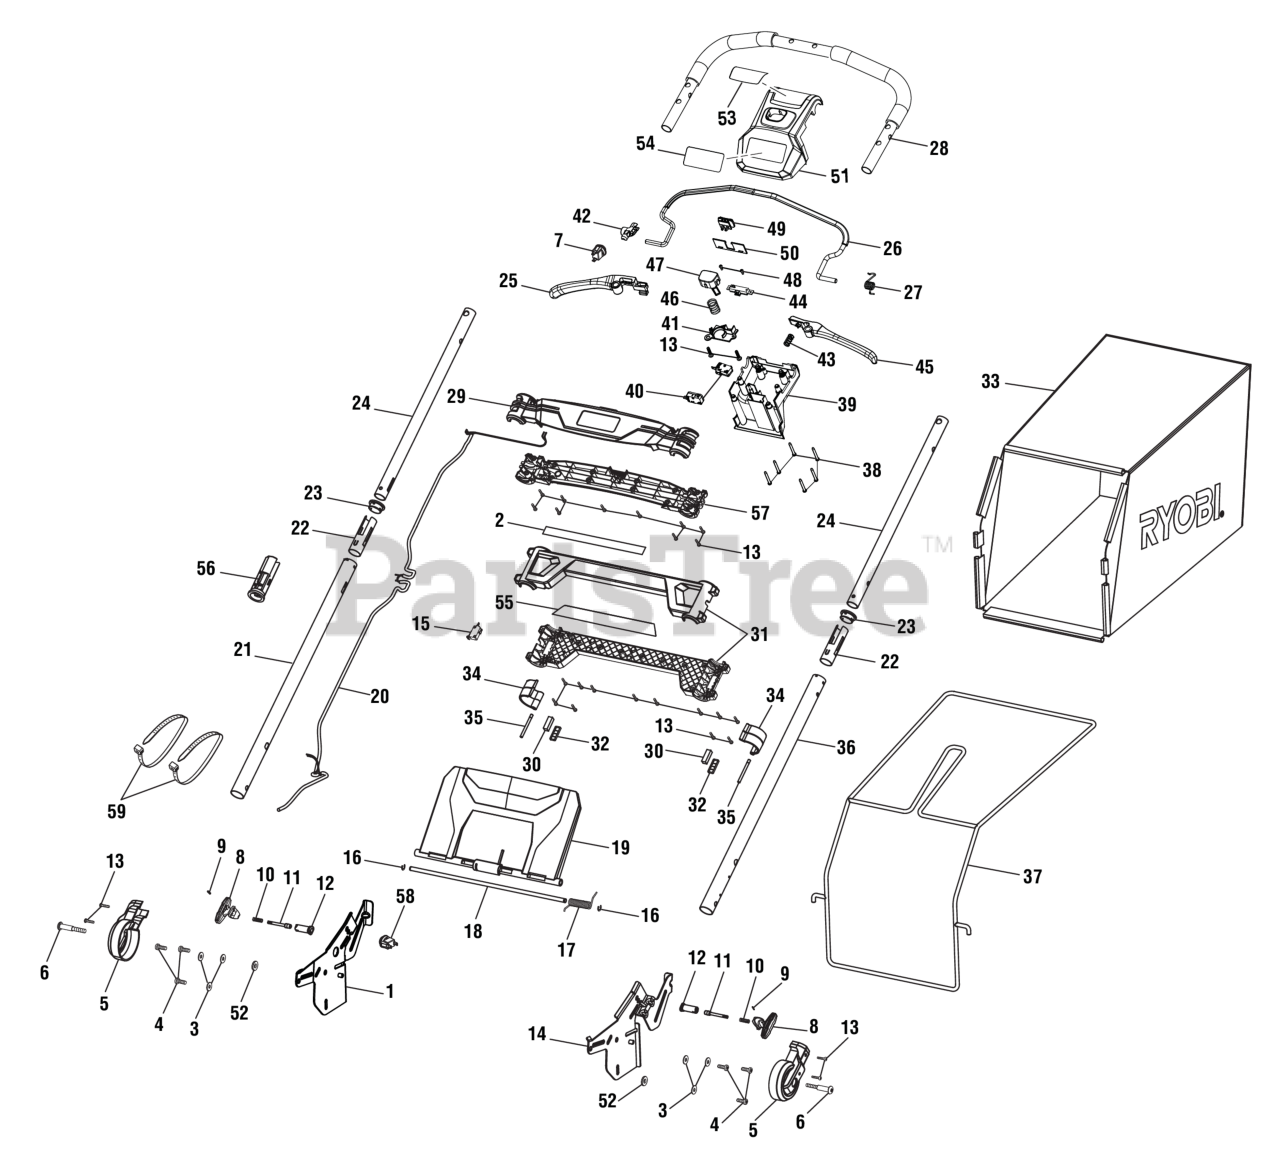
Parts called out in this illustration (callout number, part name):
1	Height Adjustment Bracket (Right)
2	Extended Handle Label
3	Washer (1/4 in., Type A)
4	Screw (1/4-15 x 3/4 in., T30 Torx Pan Hd.)
5	Hinge Cover
6	Shoulder Screw (M8 x 60 mm, T40 Torx Hd.)
7	Stop Switch (Momentary Contact)
8	Adjustment Knob (Spring Pin)
9	Spring Pin
10	Compression Spring
11	Detent Pin
12	Spring Pin Housing
13	Screw (M4 x 18 mm, T20 Torx Pan Hd.)
14	Height Adjustment Bracket (Left)
16	RETAINING RING (EXTERNAL)
17	Torsion Spring (Rear Door)
18	Rear Door Axle
19	Rear Discharge Door
20	Wiring Harness
21	Lower Handle Tube (Right)
22	Handle Tube Bushing (Large)
23	Handle Tube Bushing (Small)
24	Upper Handle Tube
25	Trigger (Right)
26	Bail Handle (Power Lever)
27	Torsion Spring
28	Upper Handle Assembly
29	Front Upper Handle Support
30	Rubber Plate (Handle Lock Clip)
31	Lower Panel Assembly
32	Block (Handle Lock Clip)
33	Bag
34	Handle Lock Clip
35	Pin (Handle Lock Clip)
36	Lower Handle Tube (Left)
37	Bag Frame
38	Screw (M4-18 x 30 mm, T15 Torx Soc. Hd.)
39	Upper Handle Support (Rear)
40	On/Off Switch
41	Spring Holder
42	Actuator Switch
43	Compression Spring
44	Variable Switch
45	Trigger (Left)
46	Safety Button Spring
47	Safety Button
48	Screw (M3 x 8 mm, Pan Hd., Pan Hd)
49	Thumb Pad
50	Dust Shield
51	Upper Handle Support Assembly
52	Washer (ID8.5 x OD20.5 x 2 mm x 2t)
53	Starting Label
54	Logo Labe
55	40V Logo Label
56	Switch Plug Housing
57	Rear Upper Handle Support
58	TOGGLE SWITCH
59	NYLON CABLE TIE
